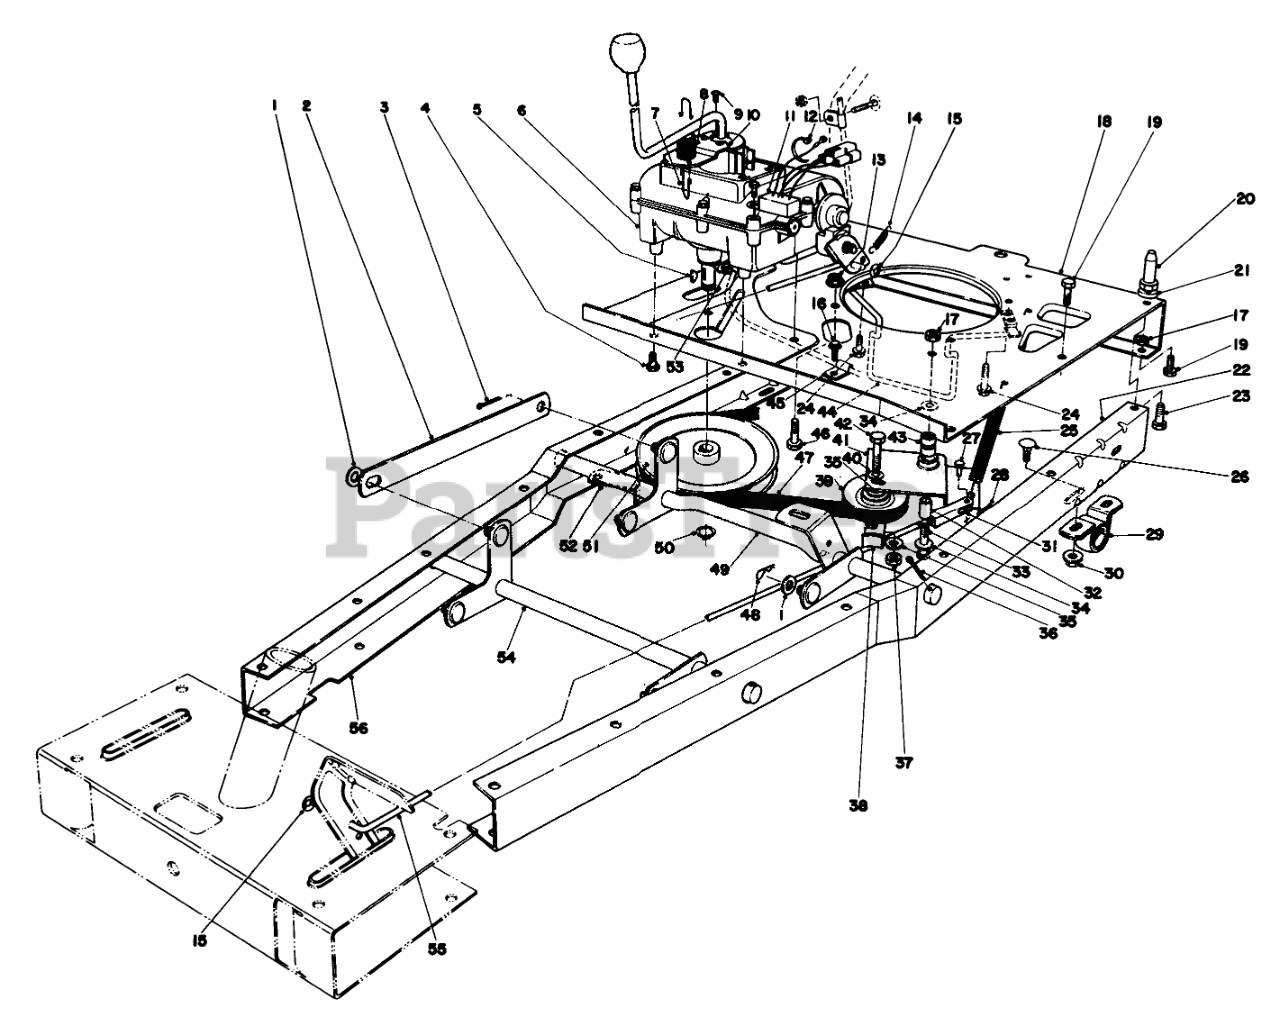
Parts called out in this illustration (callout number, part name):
1	WASHER-FLAT
2	Linkage-Height Adj.
3	PIN-COTTER
4	5/16-18 X 5/8 SEMS SC
5	KEY-WOODRUFF
6	Transmission
7	Neutral Spring Wire
8	SPRING
10	Neutral Bracket
11	INTERLOCK MODULE (B&S
12	TIE-CABLE
13	NUT-HF
14	SPRING-RETURN, BRAKE
15	PUSH ON SPEED NUT 1/4
16	SCREW
17	NUT-LOCK, CONE
18	Engine Plate
19	SCREW-HH
20	PIN-MOUNTING, LOWER
21	SPACER-PIN, MOUNTING
22	LH FRAME CHANNEL B
23	SCREW-HH
24	SCREW-HWHTF
25	Clutch Tension Spring
26	SCREW-CARR
27	PIN-CLEVIS
28	PIN-COTTER
29	PILLOW BLOCK
30	NUT-HF
32	PIVOT SPACER
33	SCREW-HH
34	WASHER-PLAIN
35	WASHER-FLAT
36	PIN-COTTER
37	NUT-LOCK, SIDE
38	RETAINER-BELT
39	PULLEY-IDLER
40	WASHER-FLAT
41	Traction Idler (Incl. Ref. #43)
42	SCREW-HH
43	Bushing
44	Belt Guide
45	CLIP-FUEL LINE
46	SCREW-HH
47	V-BELT
48	PIN-COTTER
49	REAR HT ADJ WA B
50	RING-SNAP, EXTERNAL
51	PULLEY
52	TRANS BELT RET B
53	SCREW-HHFTF
54	FRONT LIFT WA B
55	Clutch Rod
56	Frame Channel R.H.
